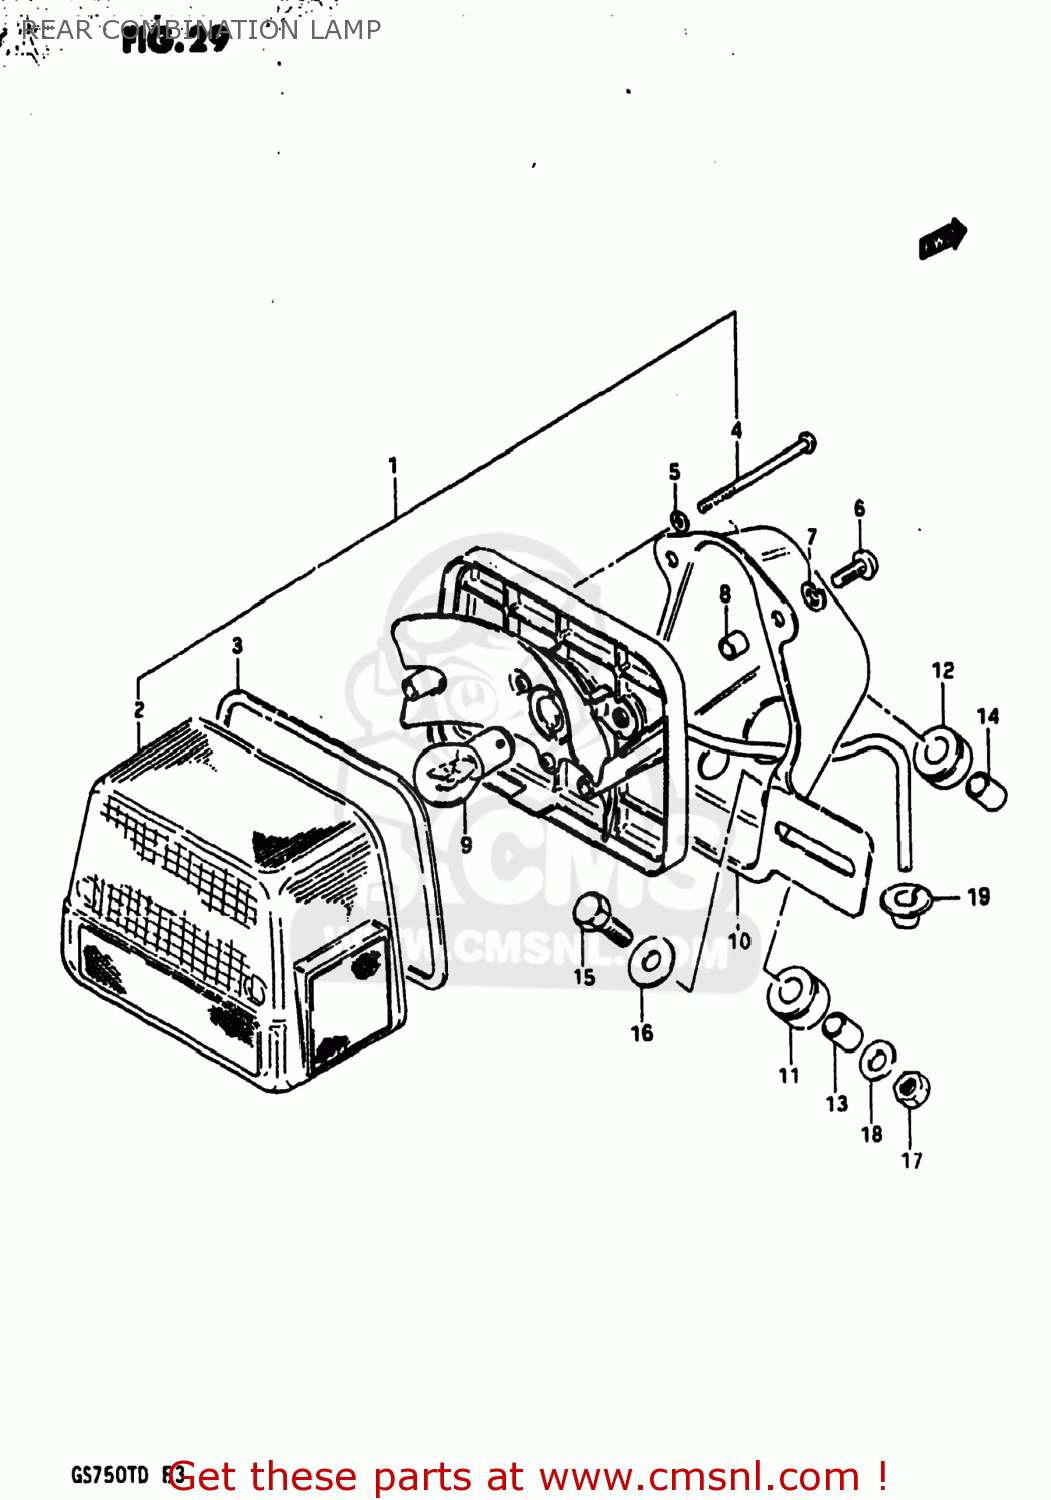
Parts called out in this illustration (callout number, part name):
1	LAMP UNIT,RR COMBNATION
2	LENS
3	GASKET (NAS)
4	SCREW
5	GASKET (NAS)
6	SCREW
7	LOCK WASHER
8	SPACER
9	BULB(12V23W)
10	BRACKET,REAR COMBINATION LAMP
11	CUSHION,REAR COMBINATION LAMP
12	CUSHION
13	SPACER,TAIL/BRAKE LAMP
14	SPACER
15	BOLT
16	WASHER (6.5X20X1.2)
17	NUT
18	WASHER
19	GROMMET
